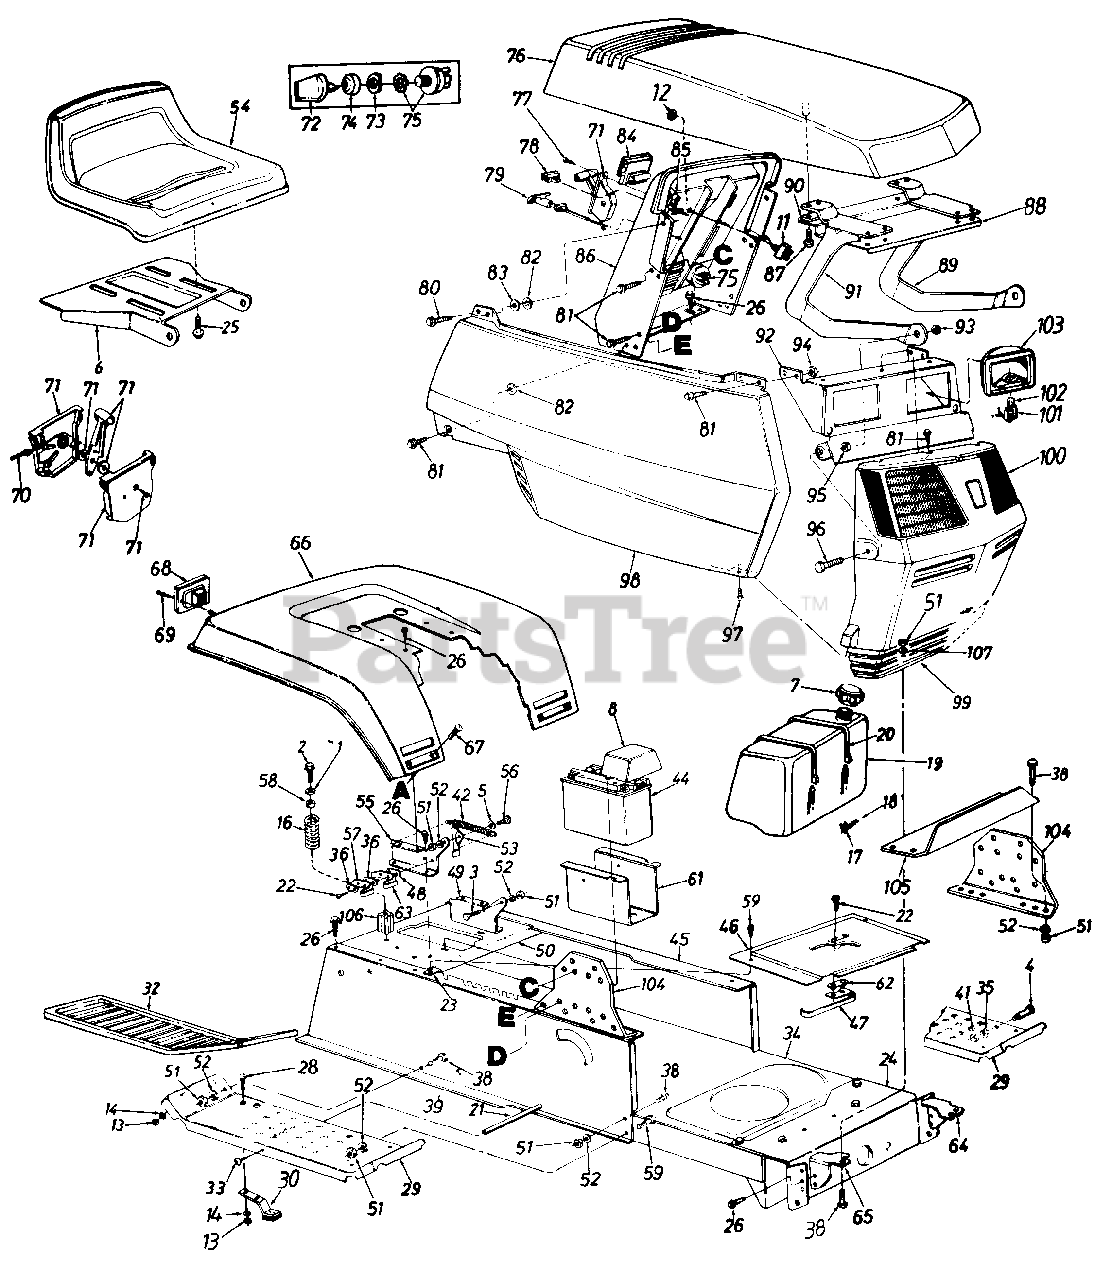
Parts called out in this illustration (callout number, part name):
1	Fl-Wash. .344" I.D. x .875"
2	Hex Wash. Hd. Tap Scr. 5/16-18 x 3.25" Lg.
3	Shld. Bolt .437" Dia. x .162"
4	Shld. Bolt .50" Dia. x .84"
5	Spr-Wash. .445" I.D. x .75
6	Seat Pivot Bracket
7	Gas Cap
8	Battery Cover
11	Toggle Switch
12	Hex Nut 1/2-27 Thd.
13	Hex Nut 1/4-20 Thd.
14	L-Wash. 1/4" I.D.
16	Compression Spring
17	Fuel Line
18	Hose Clamp
19	Fuel Tank
20	Tie Strap
21	Running Board Rod
22	Hex Wash. Hd. AB-Tap Scr. #8 x .50" Lg.
23	Speed Nut #10Z
24	Front Pivot Brkt.
25	Hex Tap Scr. 3/8-16 x .75"
26	Hex Wash. Hd. AB-Tap Scr. 5/16 x .75" Lg.
28	Carriage Bolt 1/4-20 x .62"
29	Running Board
30	Blade Brake Ass'y.
32	Rubber Foot Pad L.H.
33	Truss Mach. Scr. 5/16-18 x .75" Lg.
34	Lower Frame
35	L-Wash. 3/8" I.D.
36	Insulator Plate
38	Hex Bolt 5/16-18 x .75" Lg.
39	Upper Frame R.H.
41	Hex Nut 3/8-16 Thd.
42	Extension Spring 5.31" Lg.
44	12-V Battery (275 Cold Crank Amps)
45	Upper Frame L.H.
46	Shift Cover
47	Reverse Safety Switch
48	Insulator Boss Plate
52	L-Wash. 5/16" I.D.
53	Seat Lift Brkt.
54	Seat
56	Shld. Bolt .437" Dia. x .268"
57	Spring Switch
58	Bushing
59	Truss Hd. Scr. 5/16-18 x 1.0" Lg.
61	Battery Tray
62	Insulator Nut Plate
63	Safety Switch (Seat)
64	Grille Mount Brkt. L.H.
65	Grille Mount Brkt. R.H.
68	Taillight
69	Truss Hd. AB-Tap Scr. #6 x .62" Lg.
70	Throttle Wire 35" Lg.
71	Throttle Control Box Ass'y.
72	Ignition Key
73	Ignition Switch Nut
74	Ignition Switch Cap
75	Ignition Switch
78	Light Switch
79	Choke Control 38" Lg.
80	Hex Wash. Hd. Tap Scr. 1/4 x .75" Lg.
81	Hex Tap Scr. 1/4-20 x .5" Lg.
82	Push Nut Fastener
83	Fl-Wash. 27" I.D. x .948"
84	Ammeter
85	Speed Nut 1/4-20 Thd.
86	Dash Panel
87	Hex Wash. Hd. B-Tap Scr. 1/4 x.62" Lg.
88	Hood Reinforcement
89	Hood Hinge L.H.
94	Hex L-Nut 1/4-20 Thd.
95	Hex Jam Nut 5/16-18 Thd.
96	Hex Bolt 5/16-18 x 7/8" Lg.
97	Truss Mach. B-Tap Scr. #10 x .5" Lg.
98	Side Cover R.H.
99	Grille
100	Lens L.H.
101	Twist Lock Lamp Socket
102	Lamp
103	Headlight Housing
106	Spring Spacer
107	Fl-Wash. .343" I.D. x .687"
